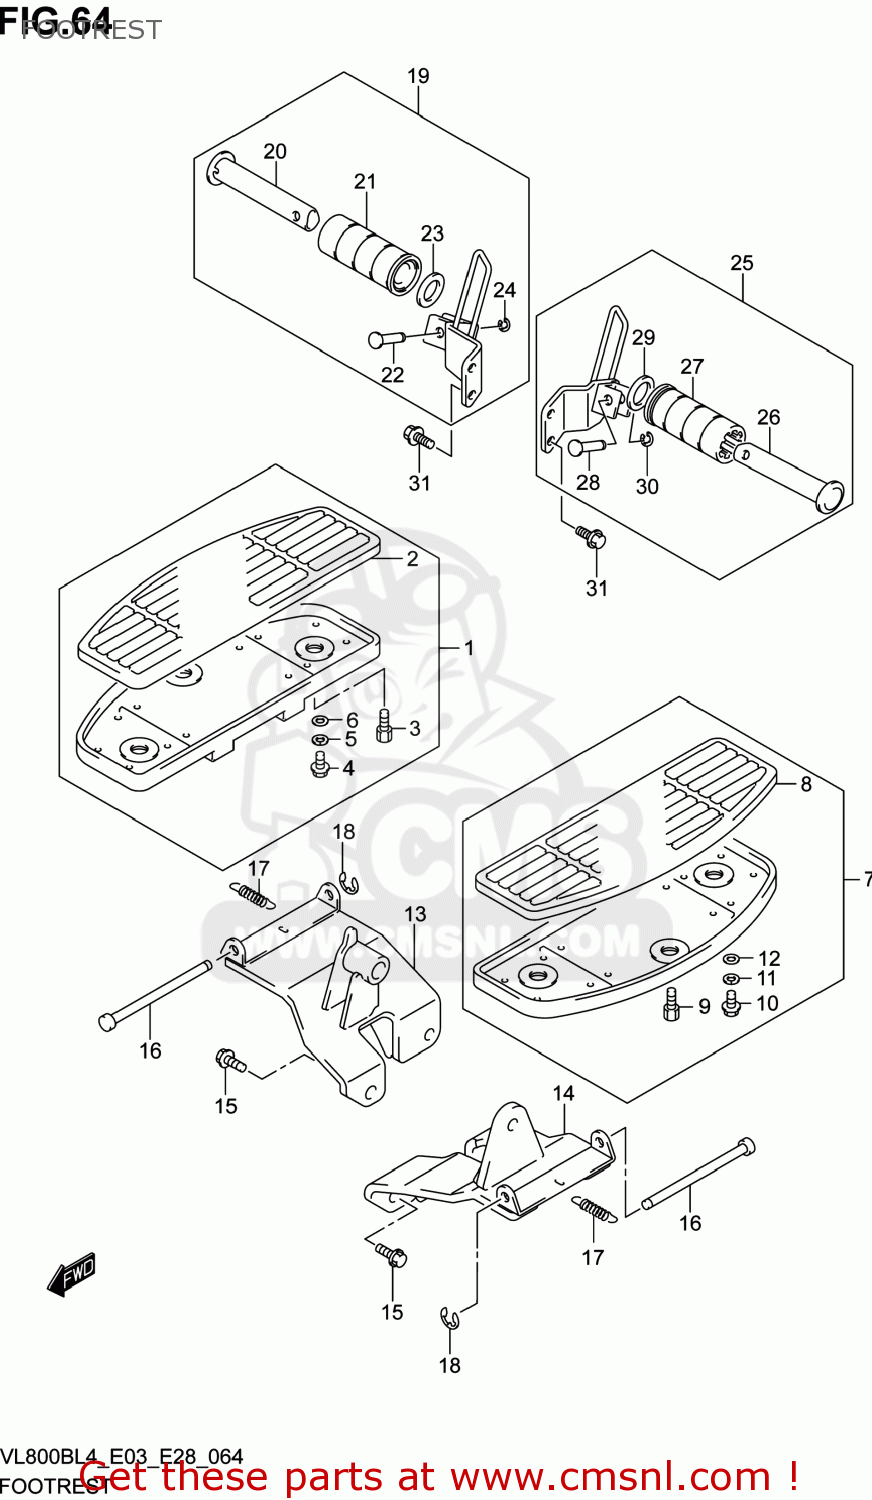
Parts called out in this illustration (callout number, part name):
1	FOOTREST ASSY,PILLION,R
2	RUBBER,FR FOOTREST
3	BOLT,BANK SENSOR
4	BOLT
5	WASHER(6.5X22X1.6)
6	CUSHION
7	FOOTREST ASSY,PILLION,L
8	RUBBER,FR FOOTREST
9	BOLT,BANK SENSOR
10	BOLT
11	WASHER(6.5X22X1.6)
12	CUSHION
13	BRACKET,FR FOOTREST,R
14	BRACKET,FR FOOTREST,L
15	BOLT
16	PIN,FR FOOTREST
17	SPRING
18	E RING
19	FOOTREST ASSY,PILLION,R
20	BAR,PILLION FOOTREST
21	RUBBER,PILLION FOOTREST
22	PIN,PILLION FOOTREST
23	WASHER(19.5X32X2)
24	E RING
25	FOOTREST ASSY,PILLION,L
26	BAR,PILLION FOOTREST
27	RUBBER,PILLION FOOTREST
28	PIN,PILLION FOOTREST
29	WASHER(19.5X32X2)
30	E RING
31	BOLT(8X16)
